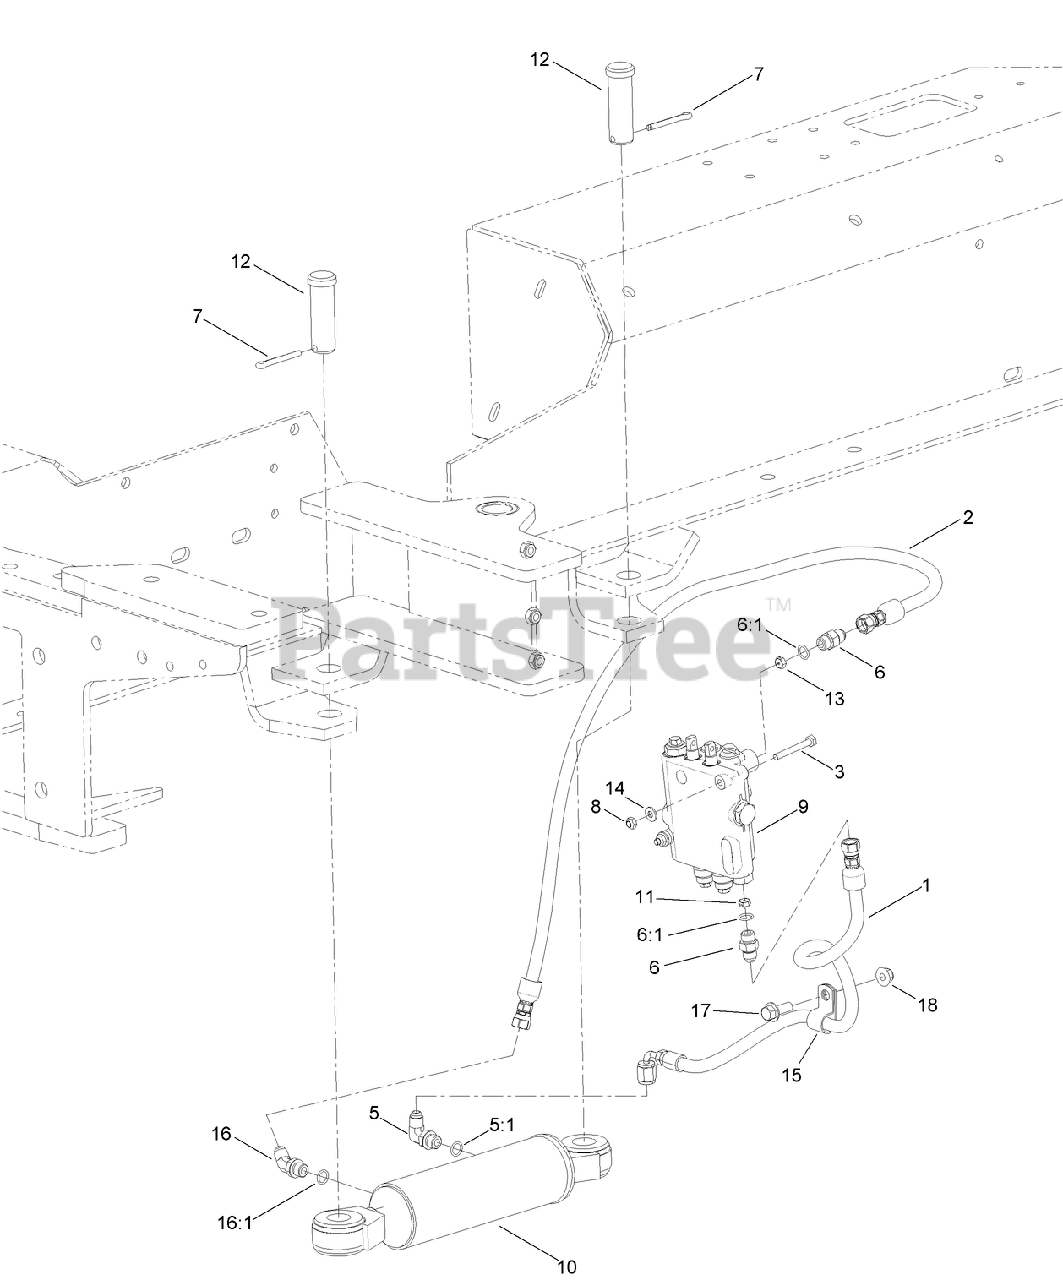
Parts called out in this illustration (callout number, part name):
1	HOSE ASM
2	HOSE ASM
3	SCREW-HH
5	FITTING-ELBOW, 90 DEG
5:1	O-RING
6	FITTING-STRAIGHT
6:1	O-RING
7	PIN-COTTER
8	NUT-LOCK, CONE
9	HYD STEERING VALVE ASM
10	HYD CYLINDER ASM
11	PLATE-ORIFICE
12	PIN-CLEVIS
13	PLATE-ORIFICE
14	WASHER-FLAT
15	CLAMP-R
16	FITTING-ELBOW, 45 DEG
16:1	O-RING
17	SCREW-HHF
18	NUT-HF, NI
